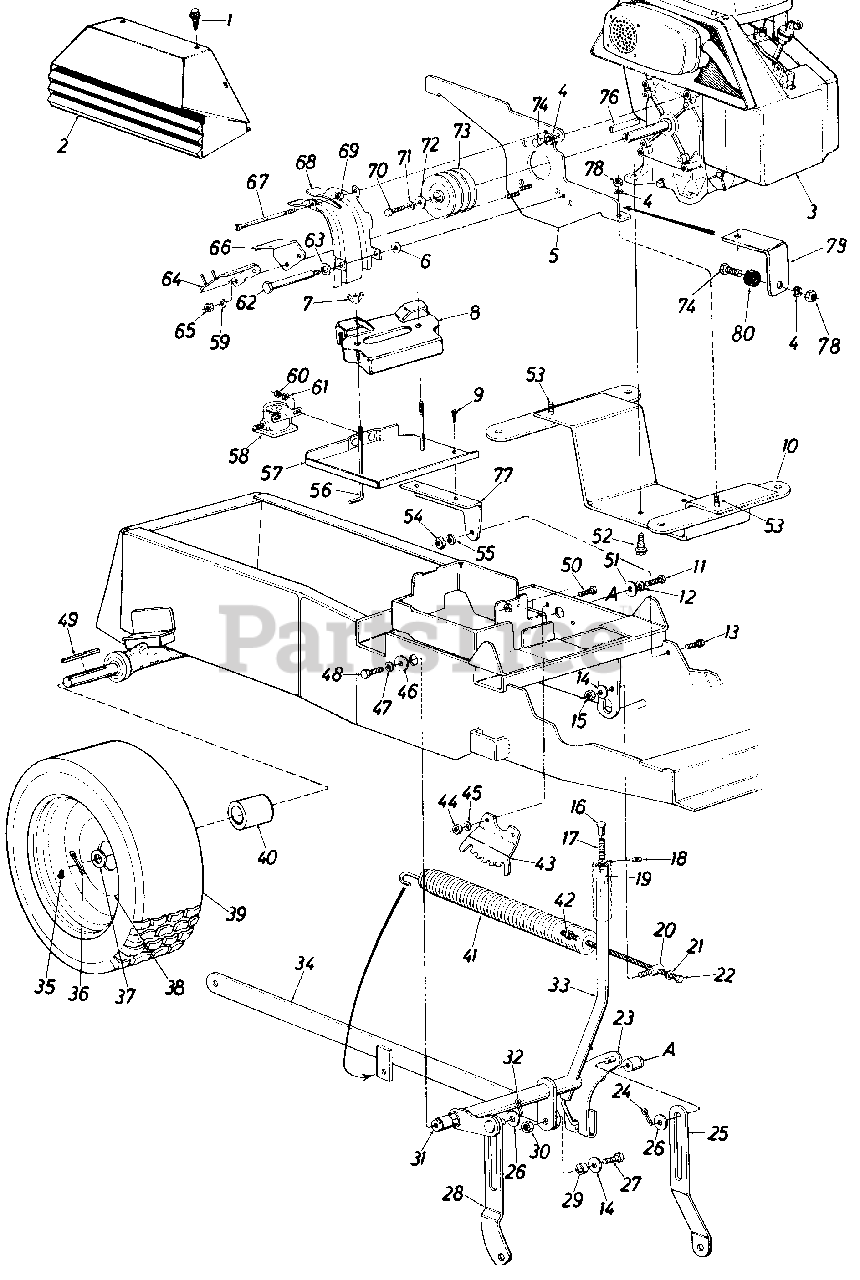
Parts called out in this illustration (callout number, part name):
1	Hex Self-Tap Scr. 1/4-20 x .75" Lg.
2	Exhaust Shield Ass'y.
3	18 H.P. Twin Cylinder Engine
4	L-Wash. 3/8" Scr.*
5	Engine Belt Guard Mount Plate Ass'y.
6	Bell-Wash.
7	Wing Nut 1/4-20 Thd.
8	Battery Cover
9	Hex Self-Tap Scr. 1/4-20 x .50" Lg.
10	Engine Support Ass'y.
11	Hex Scr. 3/8-16 x 1.00" Lg.
12	L-Wash. 3/8" Scr.*
13	Hex Sems Scr. 5/16-18 x 1.00" Lg.
14	Bell-Wash.
15	Hex Cent. L-Nut 5/16-18 Thd.
16	Lift Handle Button
17	Compression Spring
18	Fl-Wash. 1/4" I.D. x .75" O.D.
19	Locking Rod
20	Ferrule
21	Fl-Wash. 3/8" I.D. x 5/8" O.D.
22	Hex Scr.
23	Lift Shaft Pivot Pin
24	Cotter Pin
25	Deck Link-L.H.
26	Fl-Wash. 1/2" I.D. x 1-1/4" O.D.
27	Hex Scr. 1/2-20 x 1.25" Lg.
28	Deck Link-R.H.
29	Push Bar Sleeve
30	Hex Cent. L-Nut 5/16-18 Thd.
31	Lift Shaft Pivot Pin
32	Gotter Pin
33	Lift Shaft Weldment Ass'y.
34	Push Bar Ass'y.
35	Air Valve
36	Cotter Pin 3/16" Dia. x 1.50" Lg.
37	Flat Washer
41	Deck Lift Assist Spring
42	Spring Insert
43	Index Brkt.
44	Hex Nut 3/8-24 Thd.
45	L-Wash. 3/8" Scr.*
46	Fl-Wash. 3/8" I.D. x 1-1/4"O.D.
47	L-Wash. 3/8" Scr.
48	Hex Scr. 3/8-16 x 1.00" Lg.
49	Sq. Key 1/4" x 3.0" Lg.
50	Hex Scr. 3/8-24 x 1.00" Lg.
51	Fl-Wash. 3/8" I.D. x 1-1/4" O.D.
52	Hex Wash. Hd. Self-Tap Scr. 3/8-16 x 1.25" Lg.
53	Hex Scr. 3/8-16 x 1.25" Lg.
54	Hex Nut 5/16-18 Thd.
55	L-Wash. 5/16" Scr.*
56	Battery Hold Down Rod
57	Battery Carrier Ass'y.
58	Solenoid
59	L-Wash. 5/16" Scr.
60	Hex Nut 1/4-20 Thd.
61	L-Wash. 1/4" Scr.
62	Shoulder Bolt .50 Dia. x 2.625" Lg.
63	Wave Wash.
64	Engine Belt Guard Ass'y.
65	Hex Nut 5/16-18 Thd.*
66	Engine Belt Guard Ass'y.
67	Belt Guard Scr.
68	Engine Belt Guard Ass'y.
69	Hex Cent. L-Nut 5/16-24 Thd.
70	Hex Scr. 3/8-24 x 1.50" Lg. (Grade 5)
71	L-Wash. 3/8" Scr. H.D.
72	Fl-Wash. 3/8" Dia.
73	Engine Pulley
74	Hex Bolt 3/8-16 x .75" Lg.
76	Sq. Key 1/4" x 1/4" x 1.50" Lg.
77	Battery Carrier Support Brkt.
78	Hex Nut 3/8-16 Thd.*
79	Mount Brkt.
80	Engine Mount
